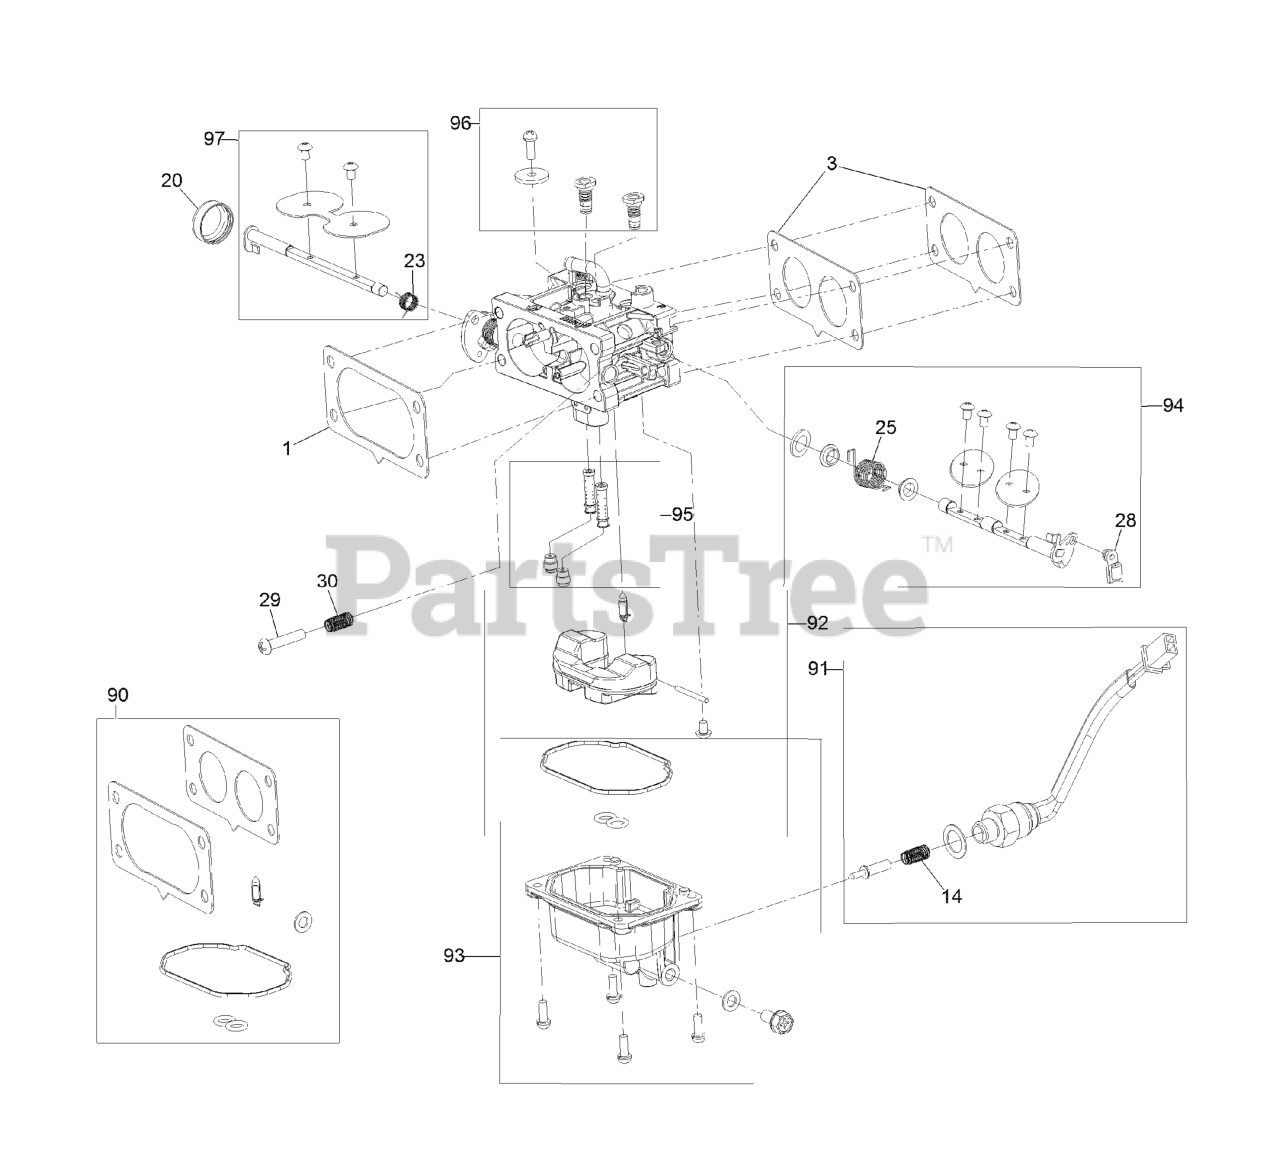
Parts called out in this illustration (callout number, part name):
1	GASKET-CARBURETOR
3	GASKET-CARBURETOR
20	COVER-SHAFT, CHOKE
28	CLAMP-LOCK
29	SCREW-PPH
90	CARBURETOR REPAIR KIT
91	SOLENOID KIT
92	FLOAT KIT
93	BOWL KIT
94	THROTTLE SHAFT KIT
95	NOZZLE AND JET KIT
96	IDLE JET KIT
97	CHOKE SHAFT KIT
